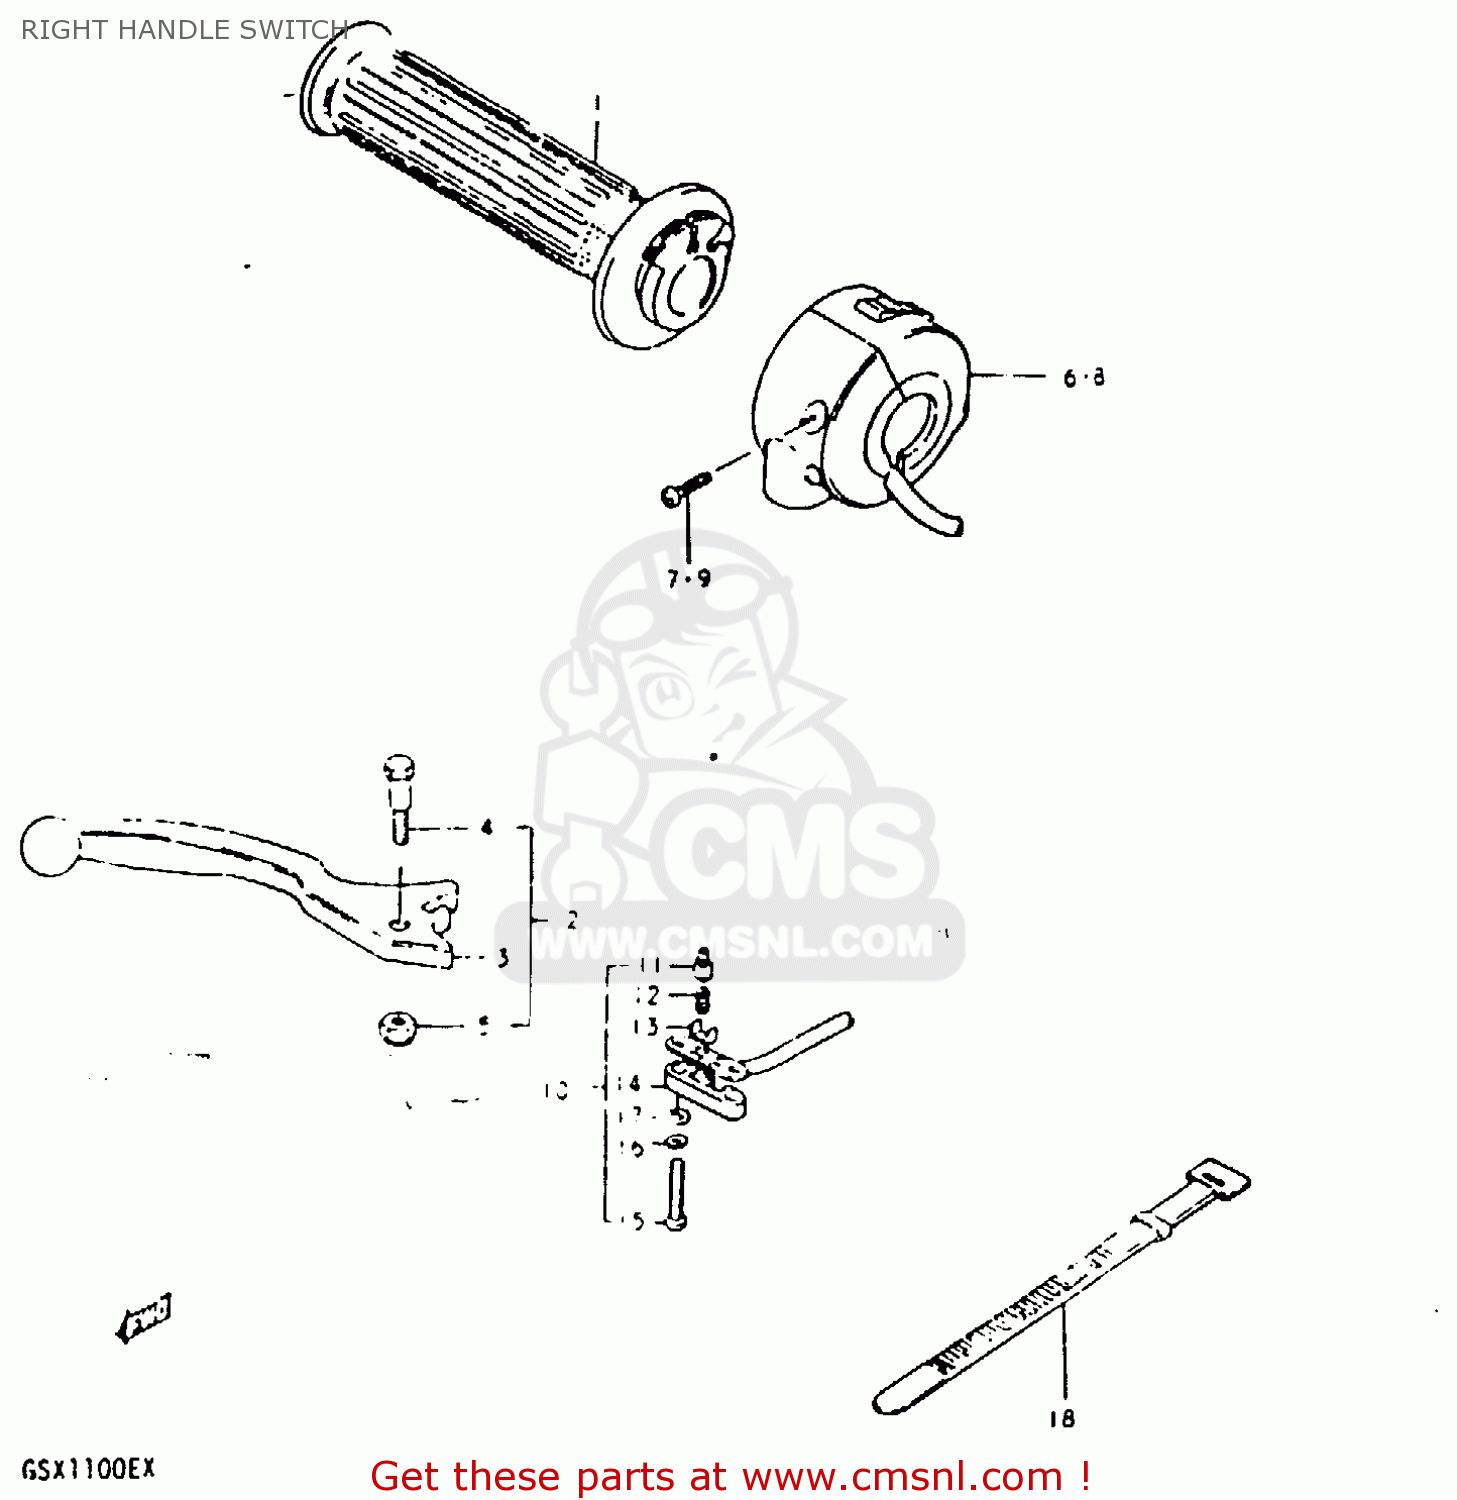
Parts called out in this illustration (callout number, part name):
1	GRIP,THROTTLE
2	LEVER ASSEMBLY,BRAKE
3	LEVER,BRAKE
4	BOLT
5	NUT 6MM
6	SWITCH ASSEMBLY,HANDLE,RIGHT
7	SCREW
18	CLAMP(L:120)
